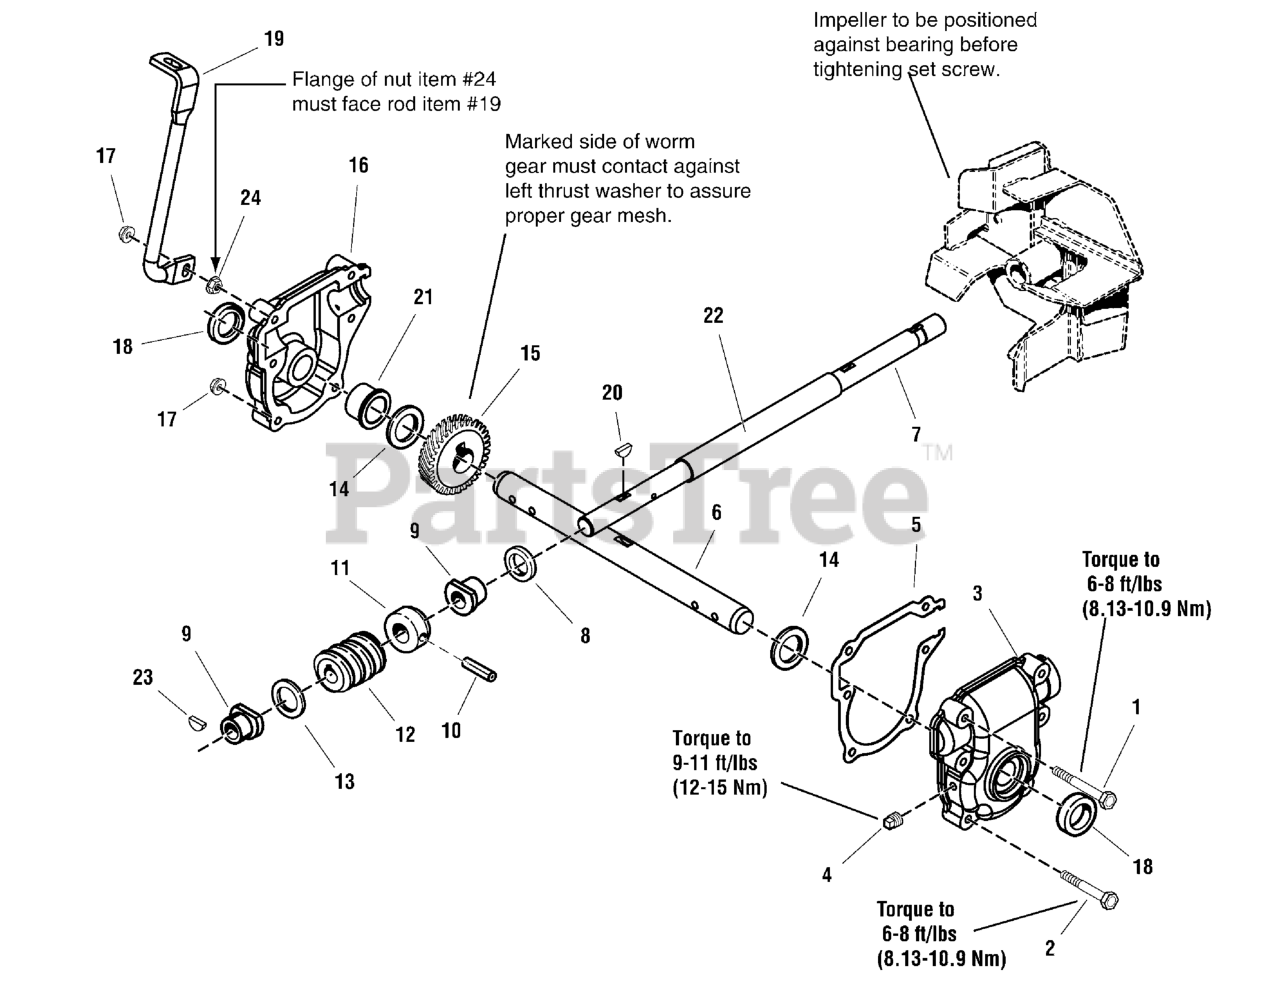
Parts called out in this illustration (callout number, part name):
1	CAPSCREW, 1/4 - 20 x 2-1/2
2	CAPSCREW, 1/4-20 x 2-1/4
3	GEAR CASE, Left
4	TAPERED PIPE PLUG
6	SHAFT, Auger Cutoff
7	SHAFT, Worm Cutoff
8	SEAL, Oil
9	FLANGE BUSHING
10	PIN, Drive Lock
11	THRUST COLLAR
12	ROLLED WORM CASE
13	WASHER, Thrust
14	WASHER, Thrust
15	GEAR, Worm
16	GEAR CASE, Right
17	NUT, Top Lock Flange, 1/4 - 20
19	BRACKET, Wireform
20	KEY, Woodruff
23	KEY, Woodruff
24	NUT, Flange, 1/4-20
